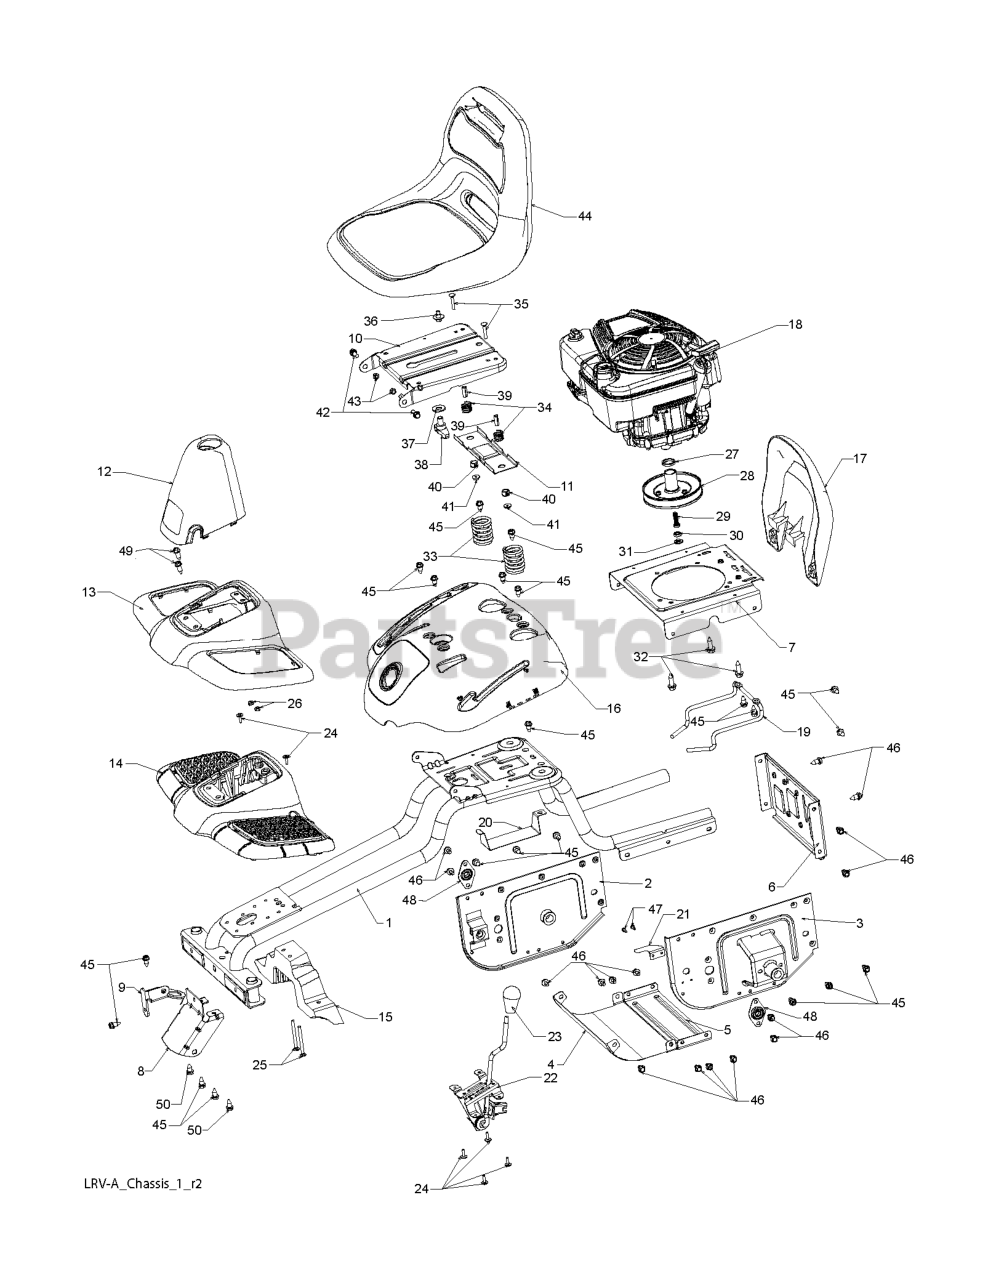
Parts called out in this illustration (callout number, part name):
1	CHASSIS.WLD.26".LRV
2	SUPPORT, AXEL LH
3	RP SUPPORT, AXLE RH
4	SHIELD, TRANSAXLE FRONT
5	STRAP.CROSS.FRICTION.DRIVE
6	COVER, FRICTION DRIVE
7	PLATE, ENGINE
8	BRACKET, CHASSIS FRONT
9	BRACKET, STEERING SUPPORT
10	PAN.ASM.SEAT.1SLOT
11	BRKT.MNTNG.SWITCH.SEAT.BLACK
12	BOOT
13	FOOTREST.AESTHETIC.WE.GRN.LRV
14	STRUCTURE, FOOT REST
15	SUPPORT, FOOT REST
16	FENDER.CNTRL.PNL.WE.GRN.LRV
17	GUARD.ENGINE.LRV
19	KEEPER, BELT
20	BRACKET, BATTERY LRV
21	LEVER, SWITCH
22	CABLE.ASM.CLUTCH.W/BRACKET
23	KNOB.OVAL.CUSTOM.BLACK
24	SCREW.#10 X 0.750.BOS
25	BOLT.CARRIAGE
26	NUT
27	SPACER.ENGINE.B&S.LRVA
28	DISC, FRICTION ASM
29	BOLT, SCKT HD 3/8-24 X 1 .25
30	BEARING.BALL.689ZZ
31	SPACER, NEUTRAL
32	BOLT 3/8-16X1-1/8
33	SPRING COMPRESSION
35	BOLT.ROUND.HEAD.SQUARE.NECK
36	BOLT,SHOULD
38	KNOB.SEAT.ADJ.WINGNUT
39	SPACER SPLIT 28X.96
41	NUT T
42	BOLT.SHOULDER.5/16-18
43	NUT.71038.31-18.HEX.NYLOCK
44	SEAT.SUBASY.OPP.WEEDEATER.LRVA
45	SCREW
46	Screw 5/16-18 x 1/2 Hex, Self Tapping 5/16-18 x 1/2
47	TAPPING SCREW
48	BEARING FLANGE BALL
49	SCREW 5/16-18X1
50	BOLT.SHOULDER.5/16-18X
